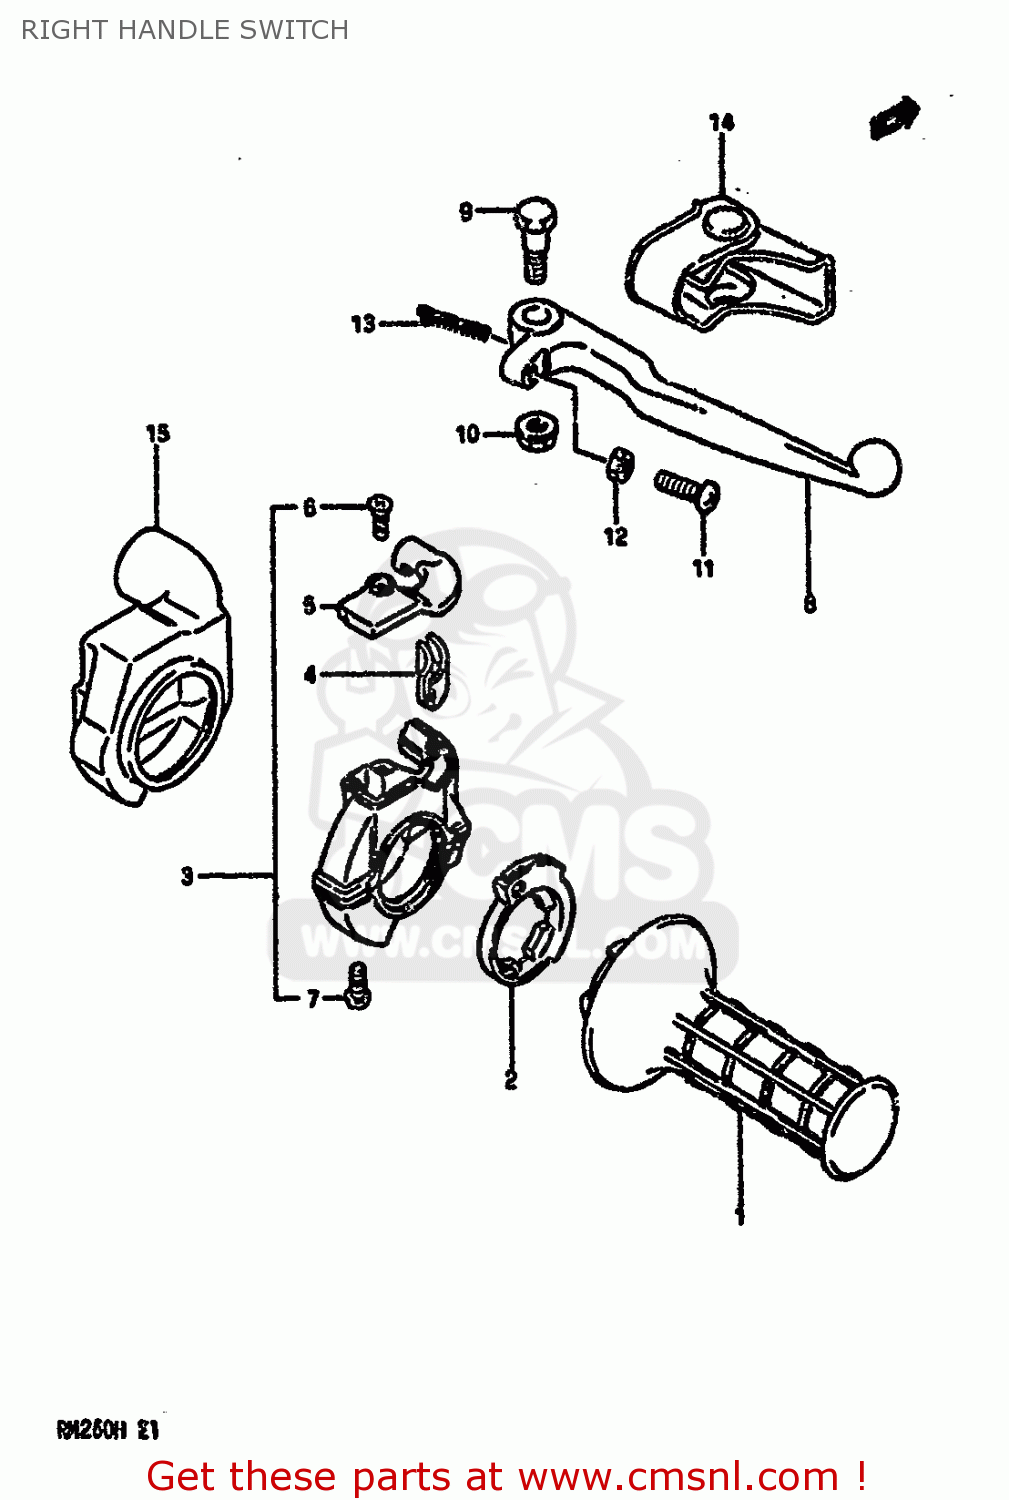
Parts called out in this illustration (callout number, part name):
1	GRIP,THROTTLE
2	ROTOR,THROTTLE GRIP
3	CASE ASSY,THROTTLE
4	GUIDE PIECE,THROTTLE
5	COVER,THROTTLE CASE
6	SCREW
7	SCREW
8	LEVER,BRAKE
9	BOLT,BRAKE LEVER
10	NUT,BRAKE LEVER
11	BOLT,ADJUST
12	NUT ,5MM
13	SPRING,RETURN
14	COVER,BRAKE LEVER
15	COVER,THROTTLE CASE
